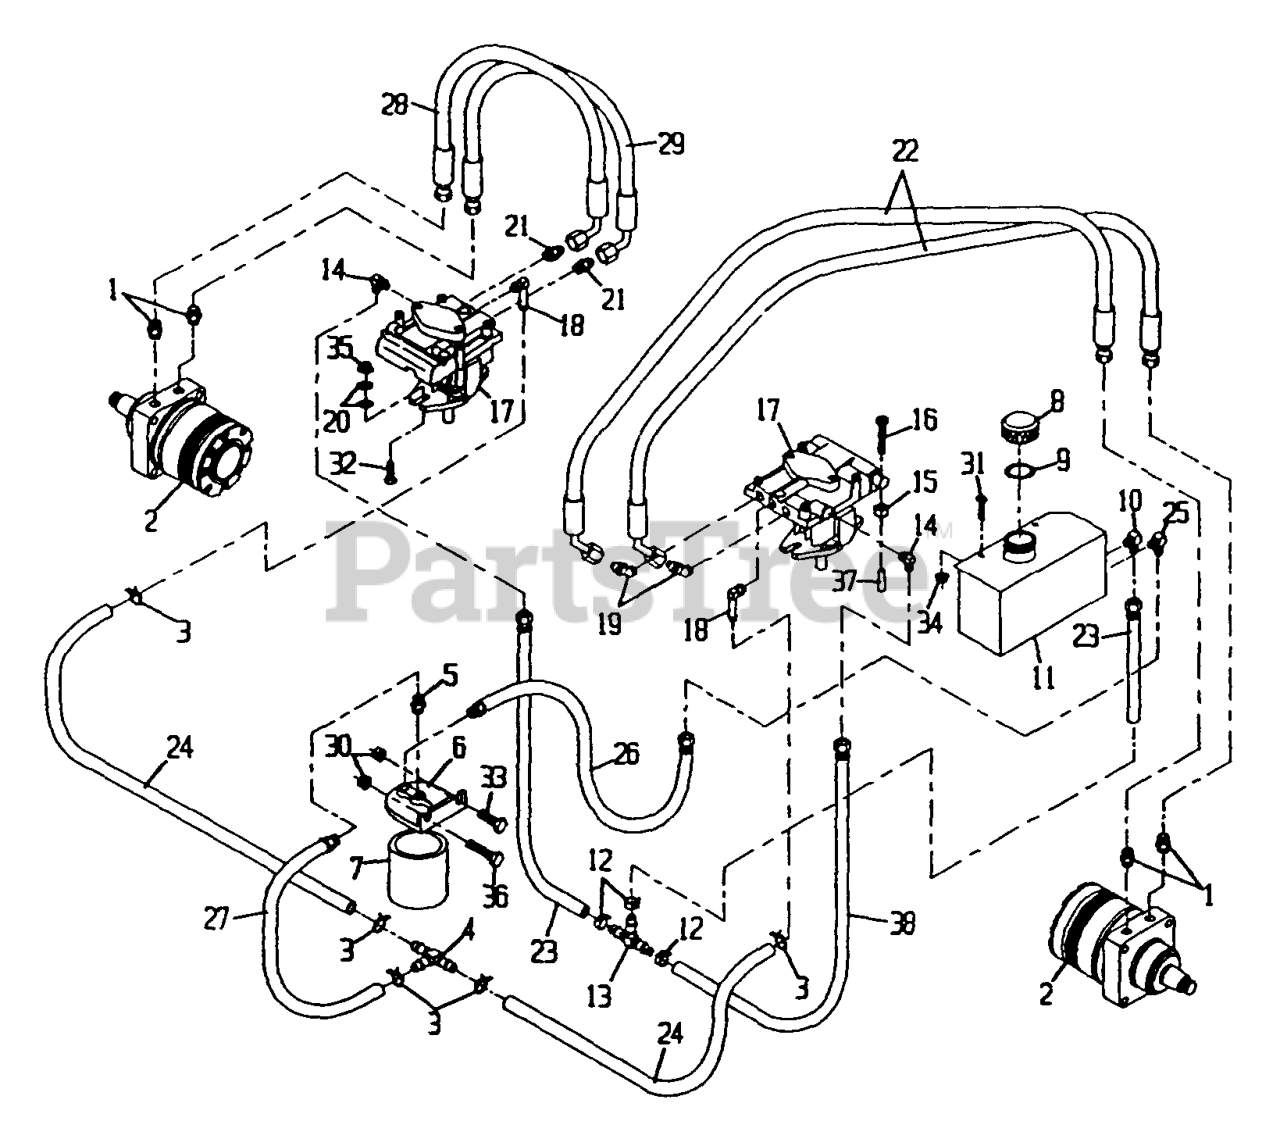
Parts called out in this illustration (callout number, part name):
1	FITTING-STRAIGHT
2	HYD MOTOR ASM
3	CLAMP-HOSE
4	FITTING-TEE, HOSE
5	FITTING-STRAIGHT
9	GASKET-CAP, TANK
10	FITTING-ELBOW
12	CLAMP-HOSE
13	FITTING-TEE, HOSE
14	FITTING-90 DEG
18	FITTING
19	FITTING-HYD, 45 DEG
21	FITTING-STRAIGHT
22	HOSE,HIGH PRESSURE
23	ASM,HOSE CASE DRAIN
24	HOSE,LO PRESSURE
25	FITTING-ELBOW
26	ASM,HOSE LO PRESSURE
27	ASM,HOSE CHARGE LINE
29	HOSE-PRESSURE, HIGH
37	GRIP-VALVE, DUMP
38	HOSE ASM
